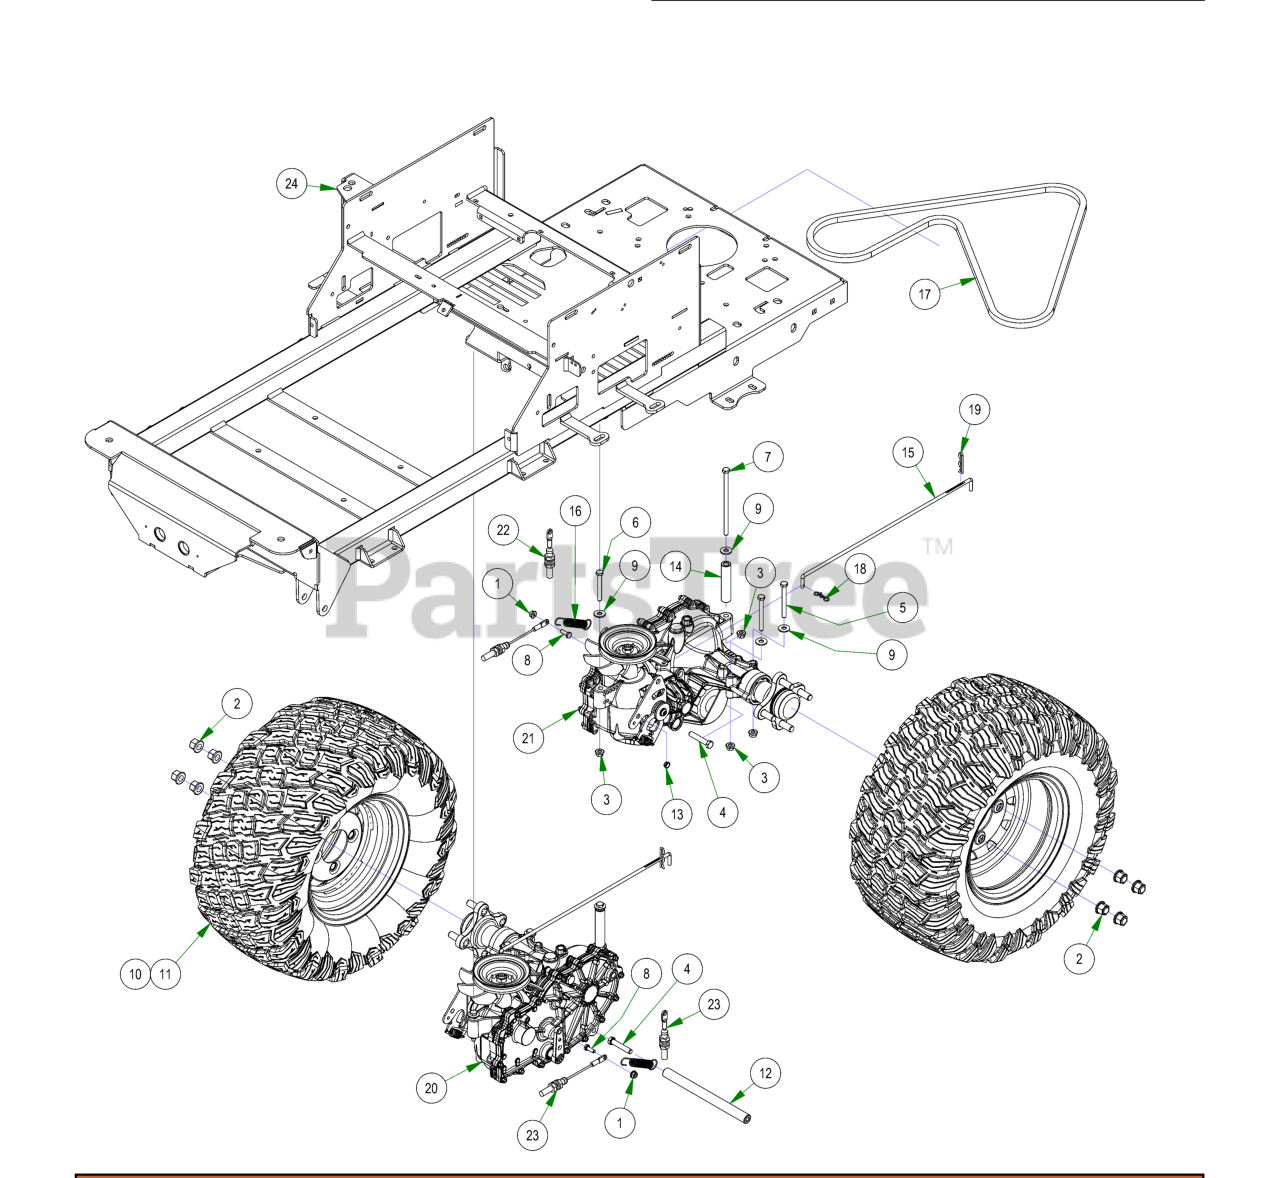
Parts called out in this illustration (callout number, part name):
1	1/4-20 NYL INSERT FLANGE LOCKNUT ZINC
2	Acorn Lug Nut
3	5/16-18 NYLON INSERT FLANGE LOCKNUT ZINC
4	3/8-16 X 2 HEX CAP SCREW (GR.5) ZINC
5	5/16-18 X 3 HEX CAP SCREW (GR.5) ZINC
6	5/16-18 X 2-1/2 HEX CAP SCREW (GR.5) ZINC
7	5/16-18 X 6 HEX CAP SCREW (GR.5) ZINC
8	1/4-20 X 3/4 HEX CAP SCREW (GR.5) ZINC
9	5/16 USS FLAT WASHER (7/8 OD) ZINC
10	22-10x10 Reaper Wheel/Tire Assembly
11	22x11-10 Reaper Rear Black Assembly
12	2017 Transaxle Spacer-ZT
13	Drive Arm Transaxle Spacer
14	2017 Transaxle Spacer
15	Neutral Rod
16	Brake Return Spring
19	Neutral Rod Clip
20	2021 RH 3100 Transaxle
21	2021 LH 3100 Transaxle
22	2021 Load Balanced Brake Cable 1
23	2021 Load Balanced Brake Cable 2
24	2024 ZT Elite Frame
